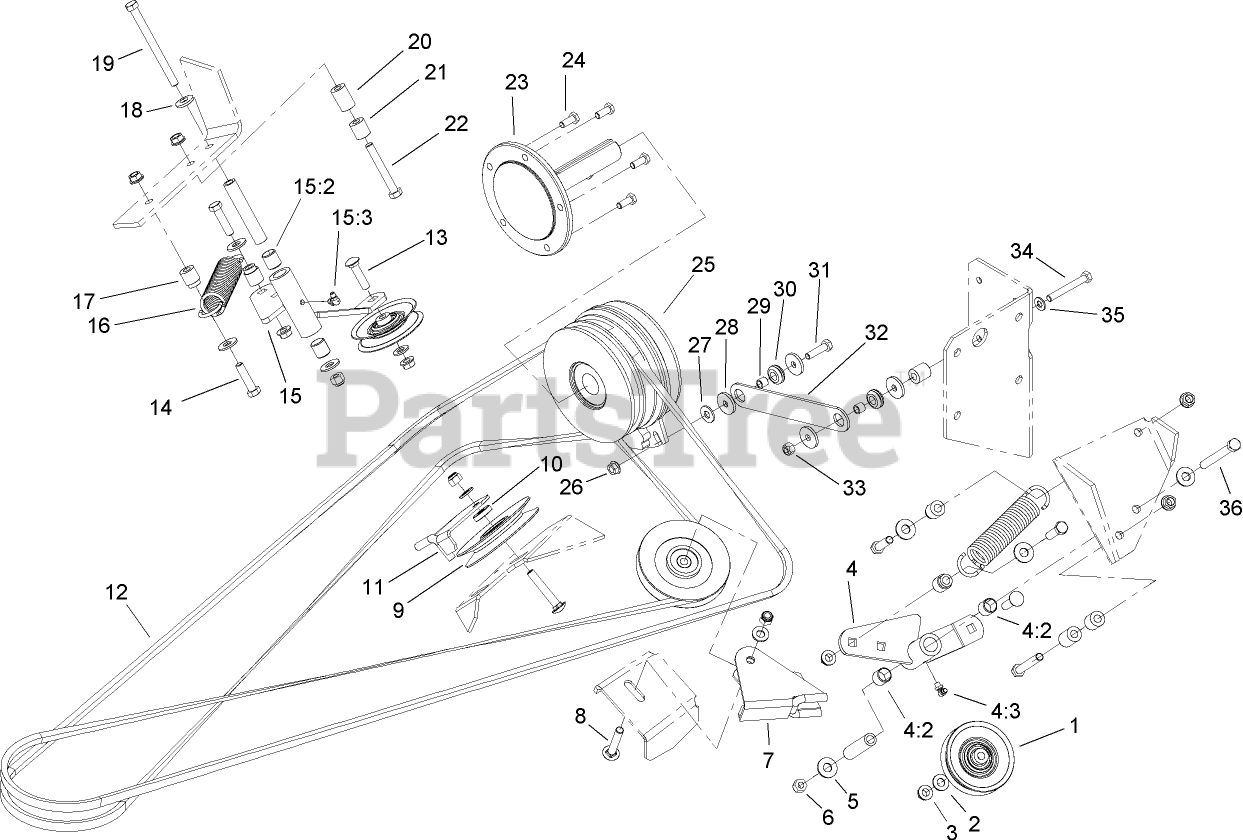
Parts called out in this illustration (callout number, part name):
1	SHEAVE
2	WASHER-FLAT
3	NUT-HHF, WHIZ
4	LH IDLER ASM
4:2	SLEEVE-BEARING
4:3	FITTING-GREASE, 90 DEG
5	WASHER-FLAT
6	NUT-LOCK, NI
7	GUARD-BELT SHEAVE, LH
8	BOLT-CARR, SHORT NECK
9	SHEAVE
10	SPACER-BRACKET, GUIDE
11	GUARD-BELT SHEAVE, RH
12	BELT-V
13	SCREW-CARR
14	SCREW-HH
15	RH IDLER ASM
15:2	SLEEVE-BEARING
15:3	FITTING-GREASE, 90 DEG
16	Spring-Extension
17	SPACER-TIGHTENER, BELT
18	WASHER-BELLEVILLE
19	SCREW-HH
20	SPACER-HYDRO CONTROL, LH
21	SPACER-STRAP, CLUTCH
22	SCREW-HH
23	SHAFT-STUB
24	SCREW-HH
25	CLUTCH ASM
26	NUT-HF
27	WASHER-FLAT
28	WASHER
29	SPACER
30	GROMMET
31	SCREW-HH
32	STRAP-CLUTCH / BRAKE
33	NUT-LOCK, NI
34	SCREW-HH
35	WASHER-PLAIN
36	SCREW-HH
